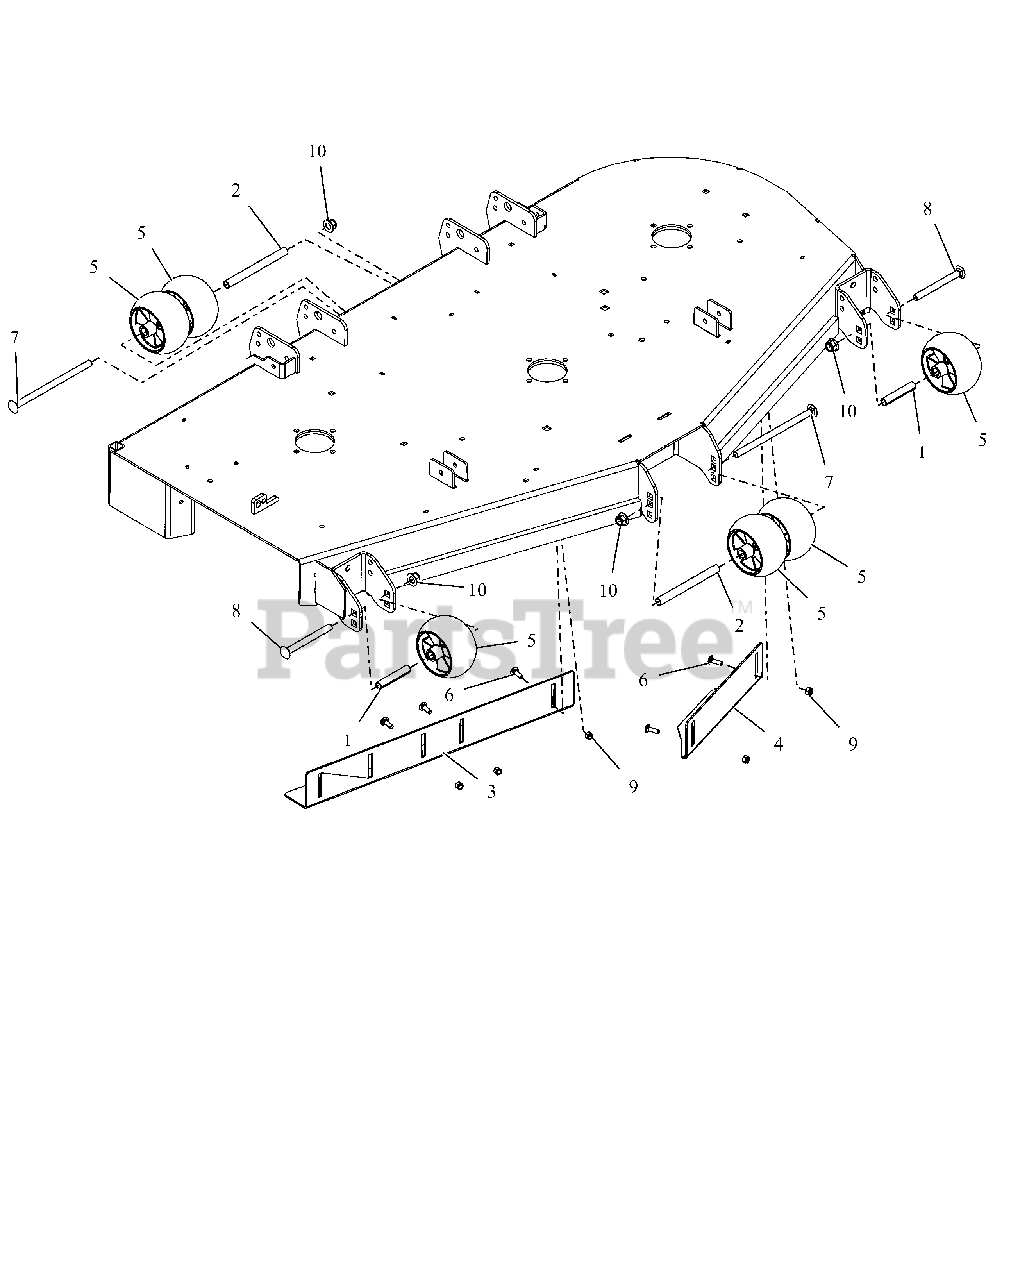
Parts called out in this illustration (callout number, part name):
1	SPACER, .510X.625X3.35
2	SPACER, .510X.625X6.50
3	60" RH VACUUM BAFFLE - RED
4	60" LH VACUUM BAFFLE - RED
5	ANTI-SCALP WHEEL - 5X3 CTR
6	@BLT-RDHDSQNK .31-18X1.00 G5YZ
7	@BLT-RDHDSQNK .50-13X8.50 G5YZ
8	BLT-RDHDSQNK .50-13X5.00 GR5YZ
9	@NUT-LK-NYL .312-18 YWZC
10	@NUT-LK-NYL-FLG .50-13 YWZC
